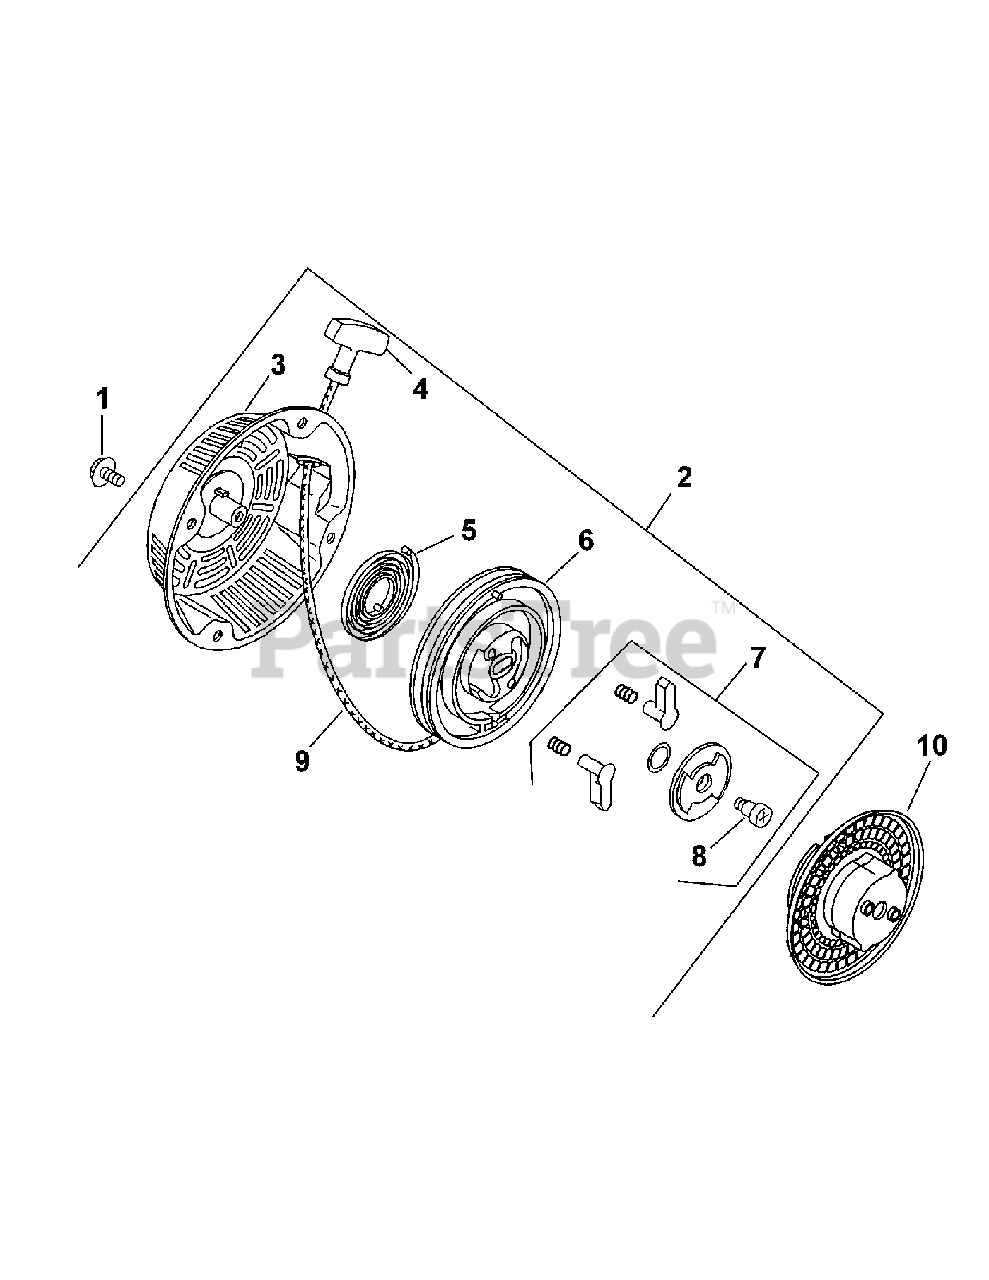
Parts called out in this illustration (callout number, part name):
2	Retractable Starter (Includes 3-9)
3	Housing Assembly
5	Spring, Starter
7	Kit, Pawl Repair (Includes 8)
9	Rope, Starting
